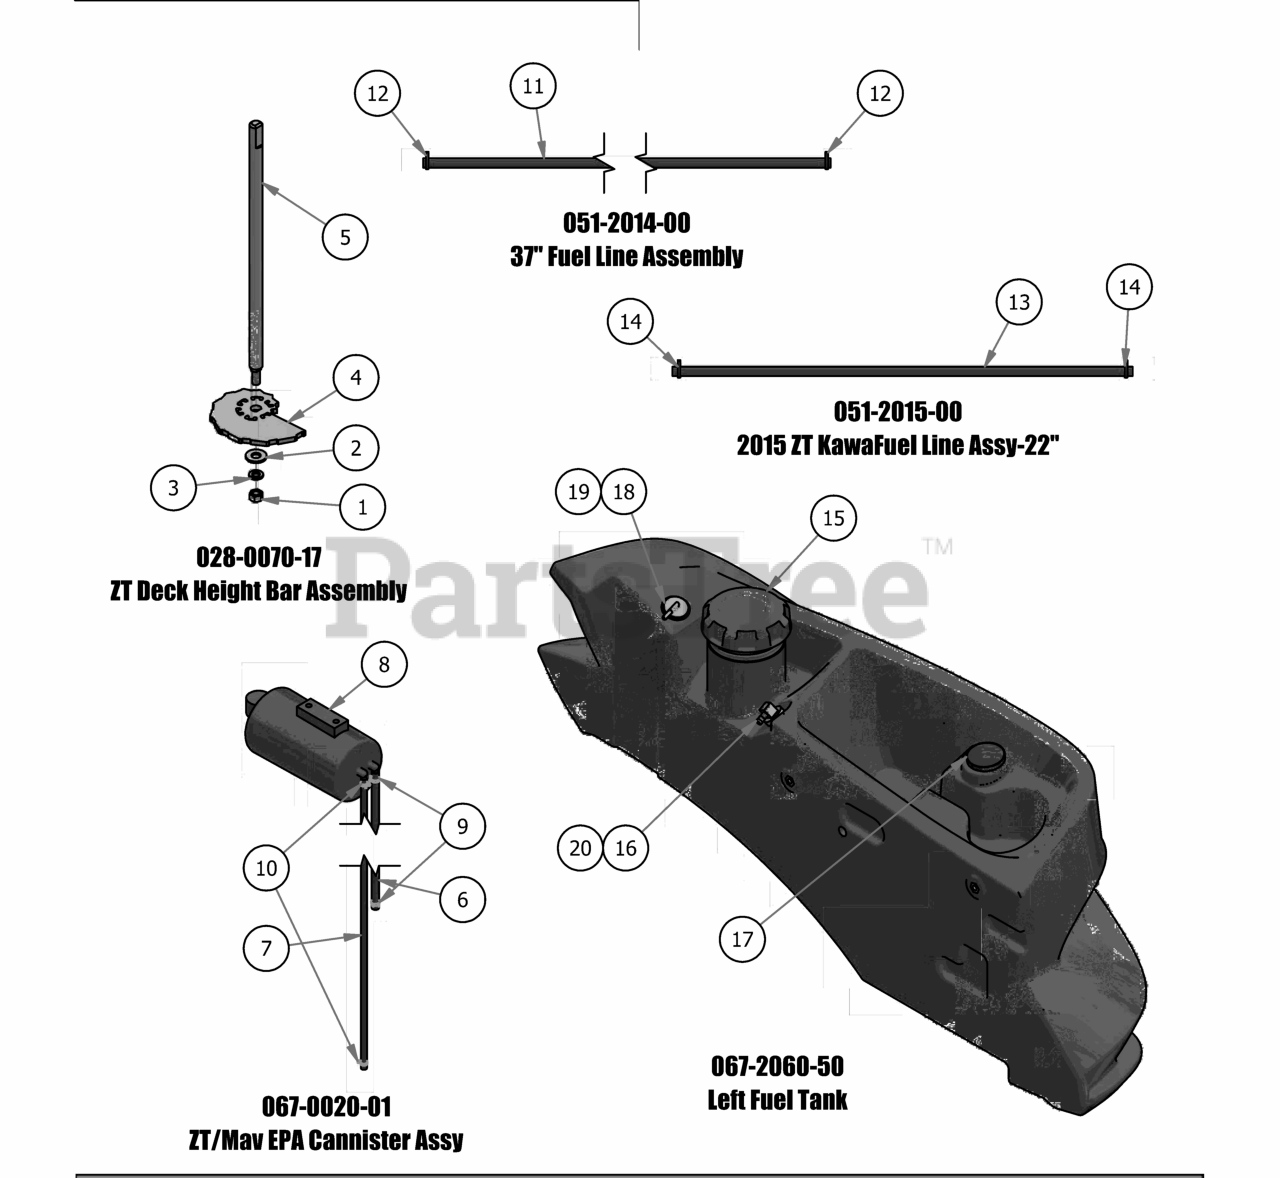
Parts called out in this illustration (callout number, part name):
1	3/8" Fine Threaded Jam Nut
2	3/8" Flat Washer
3	3/8" Lock Washer
4	2017 MZ/ZT Cam Plate
5	2017 Deck Height Dial Rod ZT
6	1/4" Vinyl Tubing, 46" Long
7	3/16" Vinyl Tubing, 55" Long
8	Carbon Canister
9	3/16 Vinyl Clamp
10	3/16" Vinyl Hose Clamp
11	37" 1/4 Fuel Line
12	1/4 Fuel Hose Clamp
13	1/4 Fuel Line
14	1/4 Fuel Hose Clamp
17	Fuel Gauge w/Grommet
18	Rollover Valve
19	Rollover Valve Grommet
20	Pick-Up Grommet
